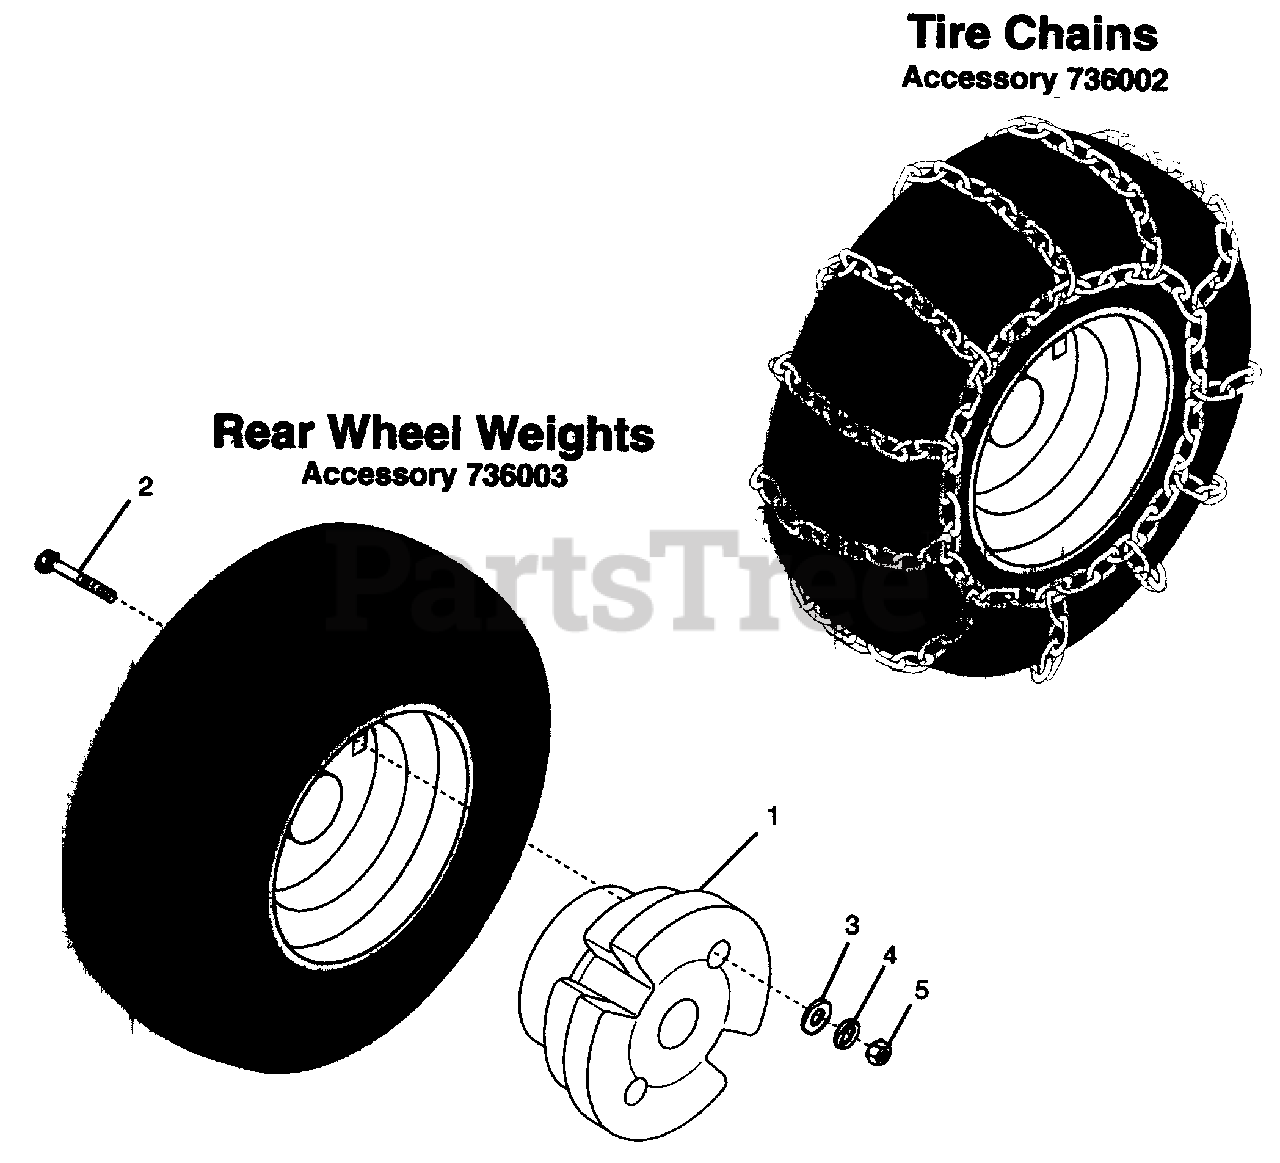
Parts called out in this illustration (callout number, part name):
1	WHEEL WEIGHT
2	@BLT-HEX .38-16X6.00 GR5 YWZC
3	WSHR-FL-STL .38X.875X.083 PL
4	WSHR-LK .375X.115 HVY PL
5	NUT-HEX .375-16
